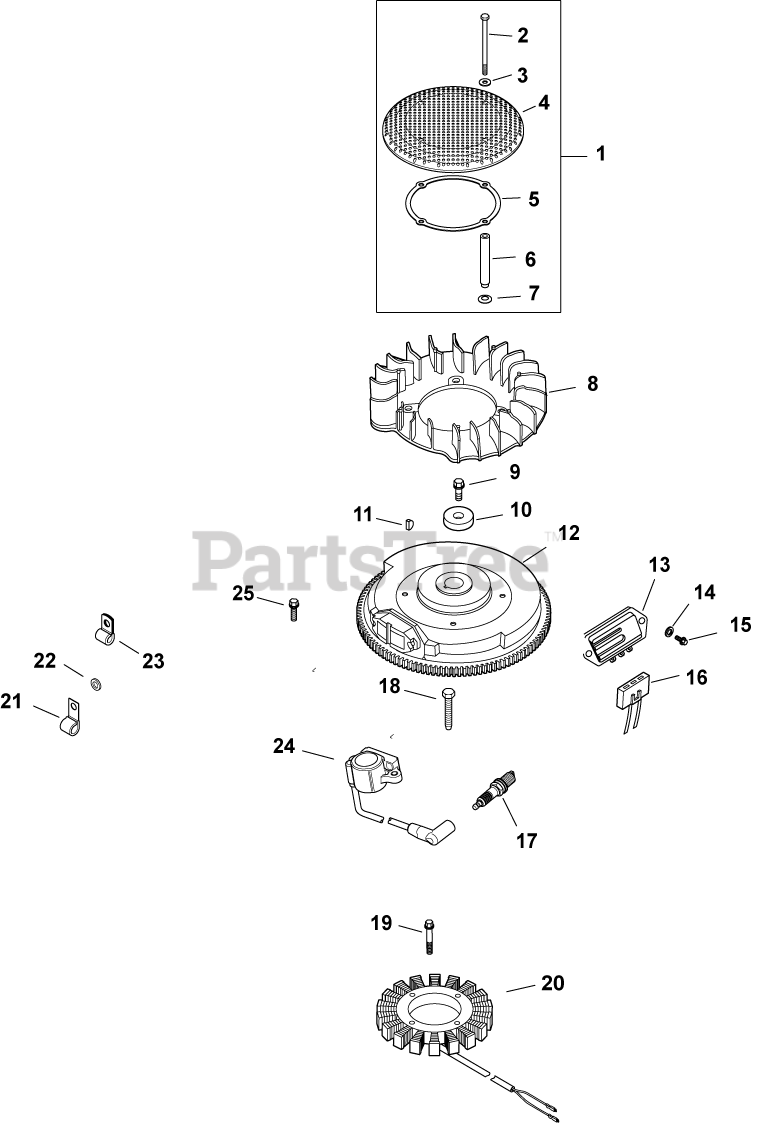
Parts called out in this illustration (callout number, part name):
1	KIT, CHOPPER SCREEN
2	SCREW, CAP M6X1.0X99.5
3	WASHER, FLAT 1/4" (O.D. 5/8")
4	SCREEN, GRASS
5	RING, SUPPORT USE 25 141 08-S
7	WASHER, SPRING 10 MM
9	SCREW, FLG M10X1.5X45 - (#25086361S)
10	WASHER, FLAT 13/32"
11	KEY, 3/16" X 5/8"
12	FLYWHEEL ASSEMBLY (LW)-USE 24 025 58-S
13	REG/RECT-15 AMP (KM)-USE 41 403 10-S
14	WASHER, FLAT 3/16"
15	SCREW, PHL HD #11-16X7/8"
16	CONNECTOR, BODY (KM)-USE 25 155 41-S
17	PLUG, SPARK (STD)
18	SCREW, M5X0.8X25 - (#25086402S)
19	SCREW, SKT SET #10-24X1/4"
20	KIT, 15 / 20 AMP STATOR
21	CLIP, TUBE & WIRING (KM)
22	WASHER, FLAT 1/4" (O.D. 1/2")
23	CLIP, CABLE
24	MODULE, IGNITION
25	SCREW, FLG THD FRM M5X.8X20-(#25086399S)
26	SCREEN, GRASS
2458452-S	MODULE, SPARK ADV -USE 24 584 89-S
